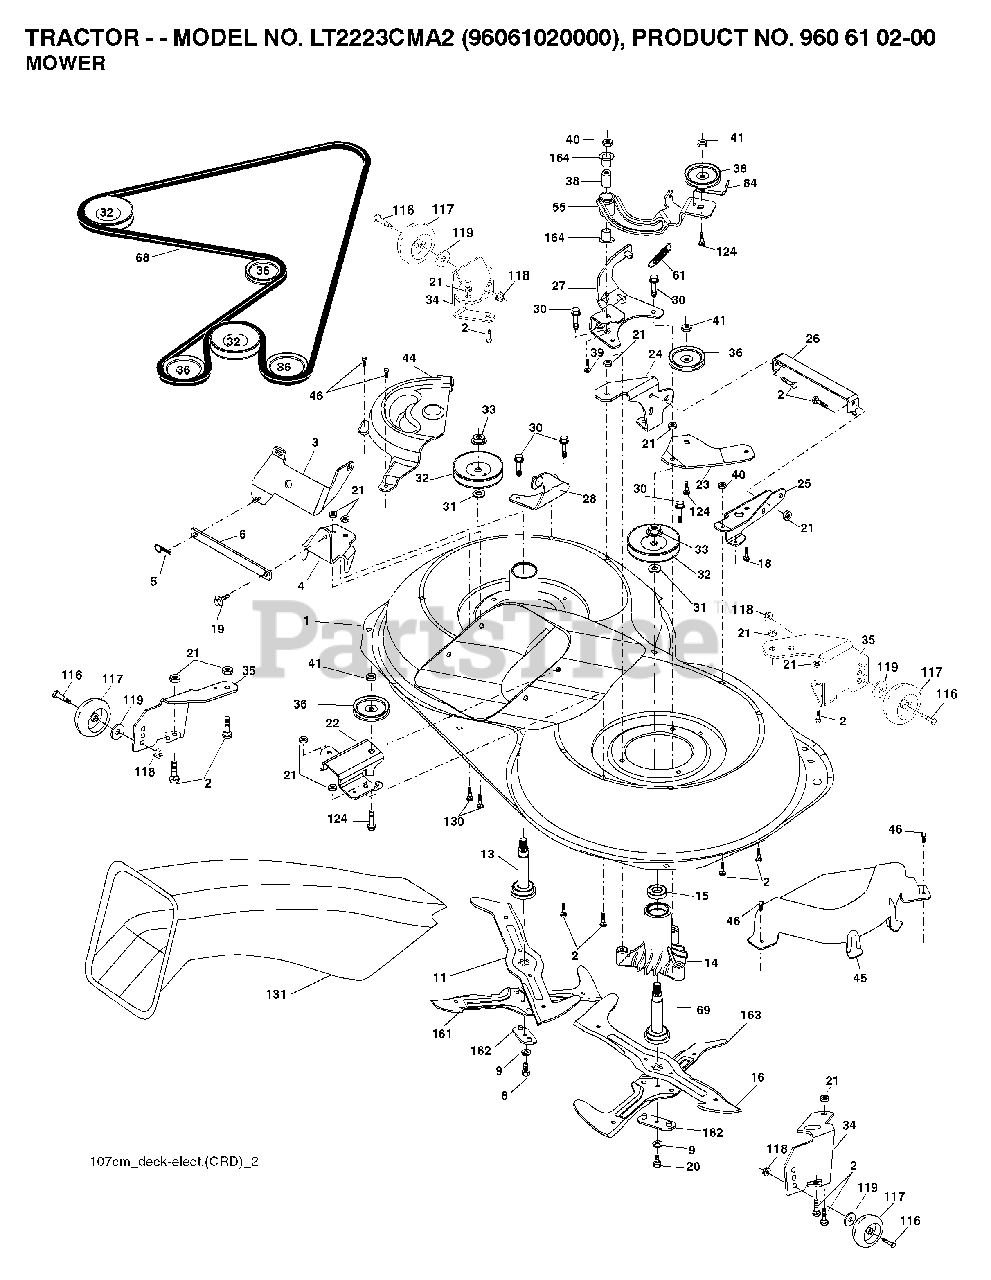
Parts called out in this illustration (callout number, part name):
2	BOLT
3	BRACKET
5	RETAINER-SPRNG RB
6	BAR SWAY
9	LOCKWASHER
11	BLADE.3N1.LH.CRD
13	SHAFT ASM VENT
14	HSG MANDREL
16	BLADE.3N1.RH.CRD
18	BOLT
19	BOLT SHD 5/16-18
21	LOCKNUT
22	BRACKET
23	BRACKET
27	BRACKET
30	SCREW, WASHER HEAD
31	WASHER.SPACER.MANDREL
33	NUT.FLANGE.LOCK.TOP
36	PULLEY.IDLER.4.25
40	LOCKNUT
41	NUT LOCK FLG 3/8-16 UNC
45	MANDREL COVER
46	SCREW.1/4-20X5/8
55	ARM IDLER
68	HEX-BELT 107 MOWER
69	SHAFT.ASM.W/LWR.BRG.RH.THREAD
84	KEEPER, BELT IDLER
116	BOLT.SHOULDER.3/8-16X3-5/8
117	WHEEL. GUAGE RALLY
118	NUT LOCK FLG 3/8-16 UNC
124	BOLT.3/8-16X1.50
131	CHUTE BAGGER
164	BRNG T
